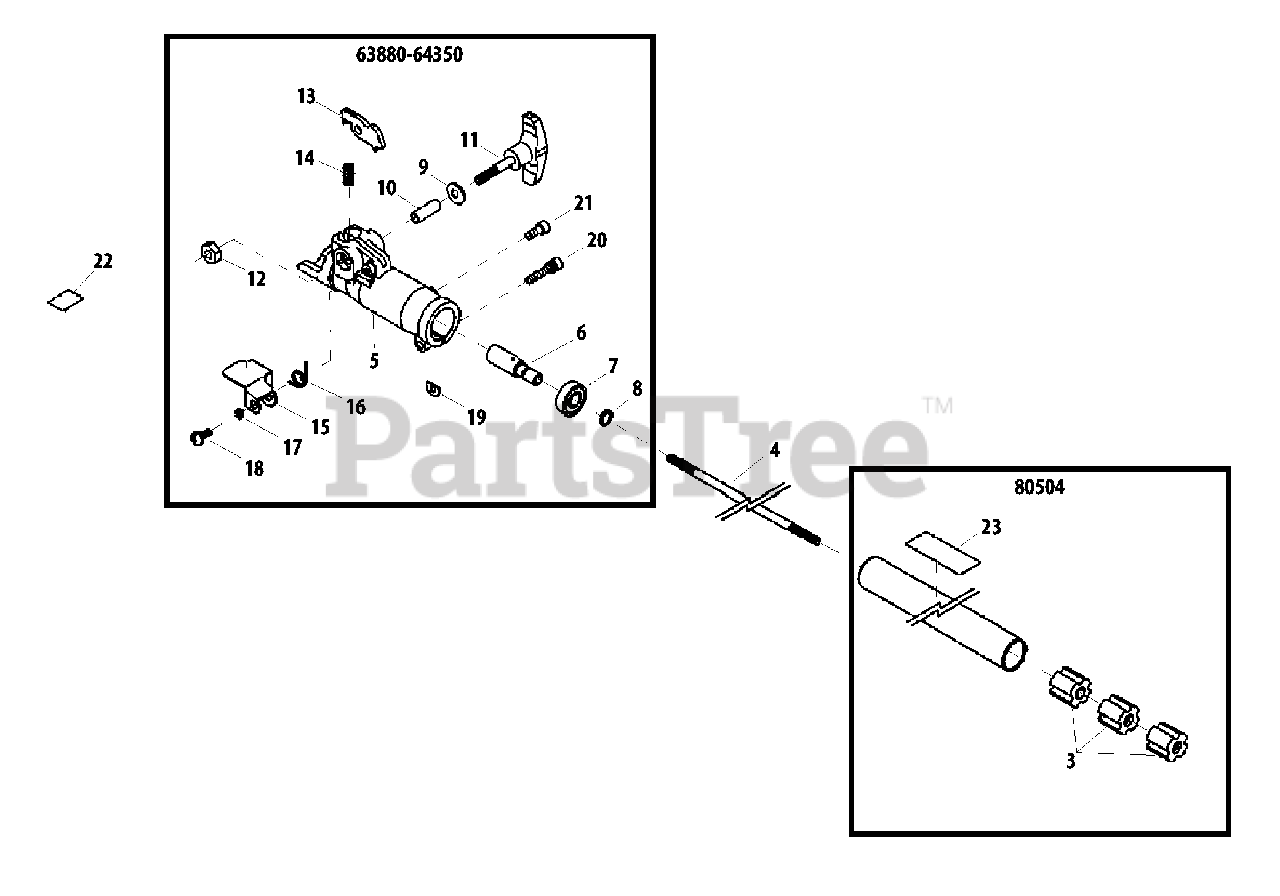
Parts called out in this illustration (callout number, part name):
3	BUSHING
4	PIPE, MAIN
5	COUPLER
6	CONNECTOR, SHAFT
7	BEARING, BALL - 609ZZ
8	RING, RETAINING
9	WASHER
10	COLLAR
11	KNOB
12	NUT
13	LEVER, LOCK
14	SPRING
15	COVER
16	SPRING
17	COLLAR
18	SCREW - 5X12
19	SHIM
20	SCREW - 5X20
21	SCREW - 5X12
22	LABEL - LATCH INSTRUCTION
23	LABEL - CAUTION
63880-64350	COUPLER ASSY
80504	MAIN PIPE ASSY
